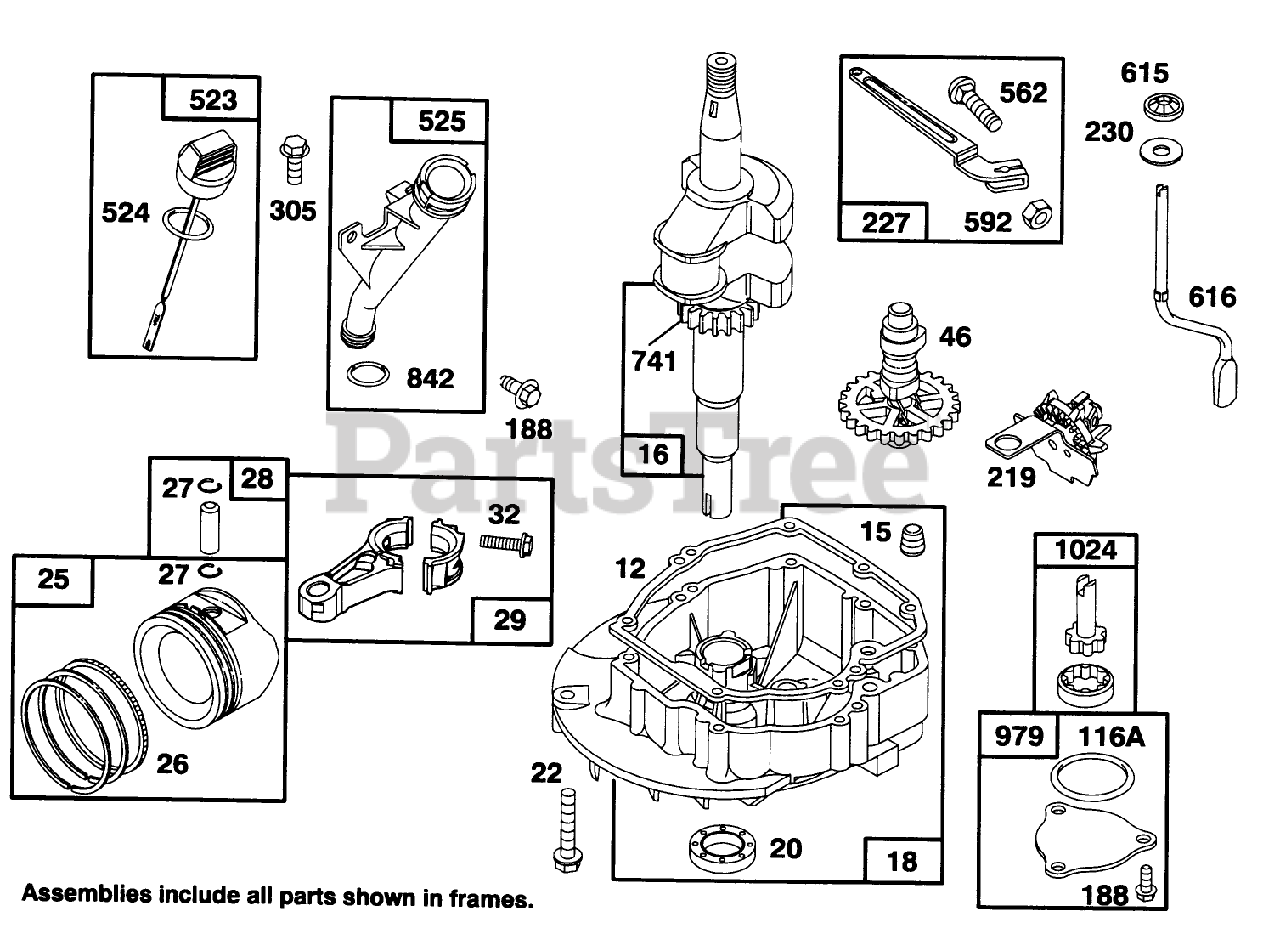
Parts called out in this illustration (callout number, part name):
12	ENGINE BASE GASKET
15	PIPE PLUG
16	CRANKSHAFT
20	SEAL-OIL
25	STD PISTON ASSEMBLY
27	PISTON PIN LOCK
29	CONNECTING ROD
116	O-Ring
188	SCREW - SEM
219	GOVERNOR/OIL SLINGER
227	GOVERNOR LEVER ASSEMBLY
305	SCREW - HEX HEAD
524	O-RING
562	GOVERNOR LEVER BOLT
592	HEX NUT
842	O-RING
979	OIL PUMP COVER
1024	OIL PUMP
